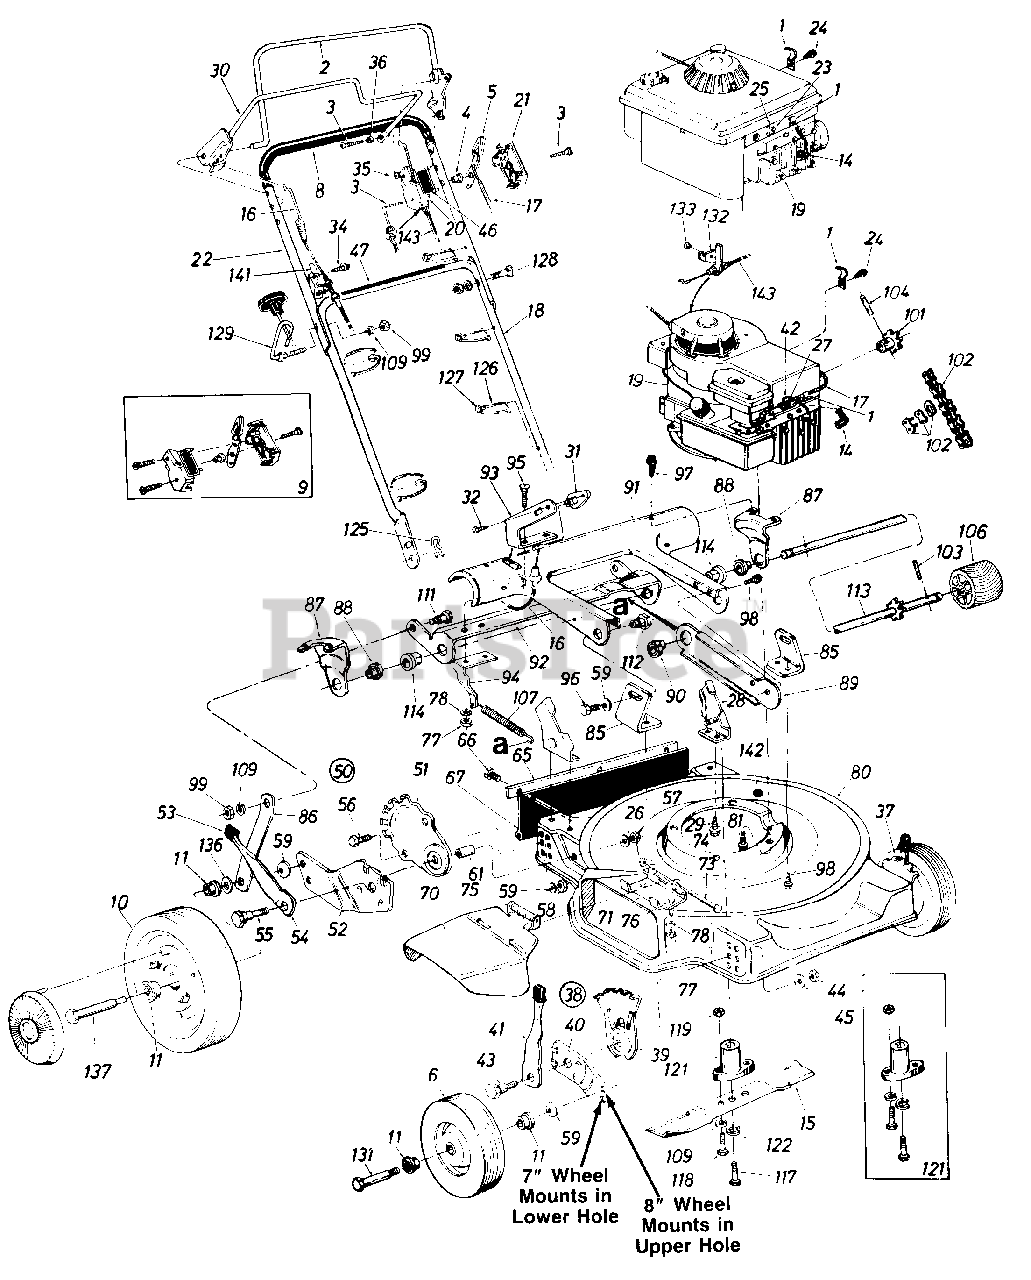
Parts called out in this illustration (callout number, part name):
1	Casing Clamp
2	Control Handle Ass'y.-L.H.
3	Truss Mach. Hi-B Tap Scr. #12 x 1.5"
4	Control Disc Pin
5	Throttle Control Lever
6	Front Wheel Ass'y. Comp.
8	Grip
9	Control Housing Comp.
10	Rear Wheel Ass'y. Comp.
11	Fl. Ball Brg 1/2" I.D.
14	Spark Plug Insulator
15	22" Blade
16	Clutch Cable w/Spring-33"
17	Throttle Wire-53"
18	Lower Handle (Chrome)
19	Engine
20	Clutch Panel Half
21	Control Panel Half
22	Upper Handle (Chrome)
23	Hex AB-Tap Scr. #8 x .50"
24	Hex B-Tap Scr. #10 x .38"
25	Casing Clamp
26	Bell-Wash. 5/16" I.D.
27	Hex "B"-Tap Scr. #10 x .38"
28	Handle Brkt. Ass'y-L.H.
29	Hex B-Tap Scr. 5/16-18 x .5"
30	S.P. Bail Ass'y.
31	Barrel Cable Hold-Down R.H.
32	B-Tap Scr. #10 x .38 Lg.
34	Hex Wash. AB-Tap Scr. 5/16 x .75"
35	Spr-Wash. .206 I.D. x .448
36	Spacer .23 I.D. x .30 O.D.
37	Front Height Adj. Ass'y.-L.H.
38	Front Height Adj. Ass'y.-R.H.
39	Height Adj. Plate
40	Pivot Bar
41	Spring Lever Ass'y. w/Knob
42	Casing Clamp
43	Shld. Bolt .50 Dia. x .430
44	Hex Nut 3/8-16 Thd.*
45	Bell-Wash. .39 I.D. x 1.38 O.D
46	Control Label
47	Instruction Label
50	Rear Height Adj. Ass'y.-R.H.
51	Index Plate
52	Pivot Bar-R.H.
53	Spring Lever Knob
54	Spring Lever
55	Shld. Bolt .50 Dia. x .433
56	Hex Bolt 3/8-16 x .75
57	Hex Cent. L-Nut 5/16-18 Thd.
58	Hex Nut 3/8-16 Thd.*
59	Bell-Wash. .40 I.D. x .88 O.D.
61	Spacer .383 I.D. x .503 O.D.
65	Retaining Strip
66	Hex AB-Tap Scr. 1/4 x .62
67	Rear Flap Ass'y.
70	Chute Deflector Ass'y.
71	Adapter Plate
73	Pivot Pin
74	Push Nut 1/4"
75	Torsion Spring
76	Hex Bolt 1/4-20 x .50 Lg.
77	Hex Nut 1/4-20 Thd.
78	L-Wash. 1/4 I.D.
80	22" Deck Ass'y.
81	Hex TT-Tap Scr. 3/8-16 x 1.0
85	Pivot Brkt.
86	Link
87	Axle Brkt.
88	Fl. Ball Brg. 1/2" I.D.
89	Brg. Support
90	Fl. Ball Brg. 1/2" I.D.
91	Pinion-Pivot Cover
92	Drive Engagement Cam
93	Engagement Arm-L.H.
94	Spring Bracket
95	Carriage Bolt 1/4-20 x .62
96	Hex Bolt 3/8-16 x .50 Lg.
97	Hex AB-Tap Scr. 1/4 x .62
98	Hex AB-Tap 1/4 x .62"
99	Hex Nut 5/16-18 Thd.
101	1OT Sprocket Ass'y.
102	#48 Chain 1/2" Pitch 50 Links
103	Spring Pin Spir. 3/16 Dia. x 1.25
104	Spring Pin Spir. 3/16 Dia. x 1.0
106	Drive Pinion
107	Extension Spring 4.25 Lg.
109	L-Wash. 5/16 I.D.*
111	Shld. Bolt .437 Dia. x .162
112	Shld. Nut .625 Dia. x .165
113	Pinion Shaft w/7T Sprocket
114	Fl. Ball Brg. .501 I.D.
117	Hex Bolt 3/8-24 x 2.25
118	Hex Bolt 5/16-24 x 1.0-Spec.
119	Hex Nut 5/16-24 Thd.
121	Blade Adapter Kit
122	L-Wash. 3/8 I.D.-H.D.
125	Intern. Cot. Pin 5/16 Dia.
126	Cable Tie
127	Cable Anchor
128	Curved Carriage Bolt 5/16-18 x 1.38" Lg.
129	Rope Guide Bolt
131	Front Axle Bolt
132	Cable Bracket
133	Pop Rivet .156" Dia. x .379
136	Fl-Wash. .531 I.D. x .93 O.D.
137	Rear Axle Bolt
141	Cable Brkt.
142	Plastic Plug
143	Control Cable-39" (Green)
